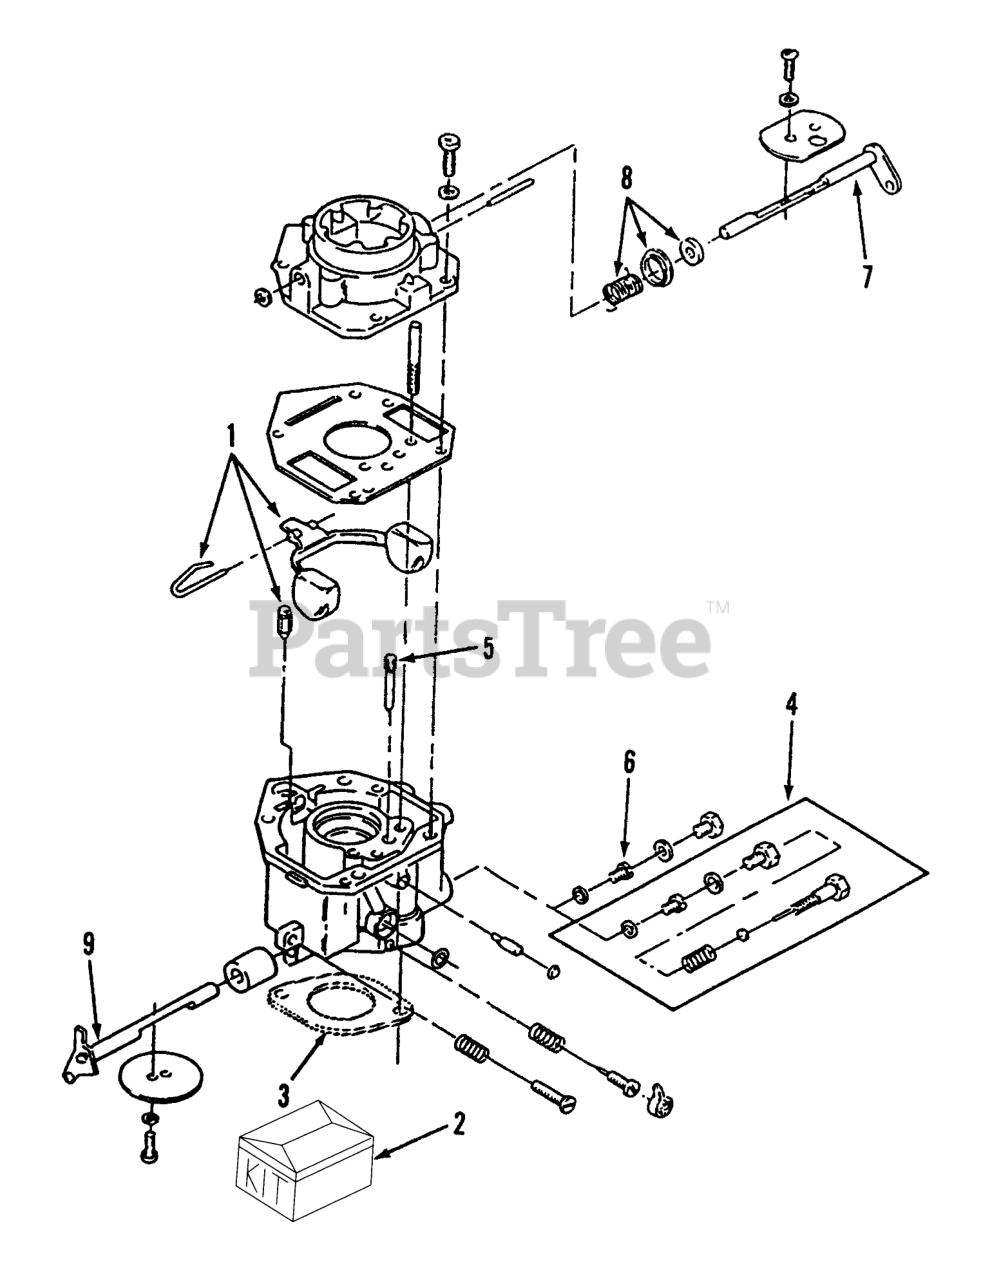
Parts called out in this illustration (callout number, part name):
1	Kit-Float (Includes Float, Pin,& Valve)
2	Kit-Repair (Includes Screw & Plug Package, Gasket Package, Float Valve, Idle Adjust Needle & Spring, Mounting Gaskets, & Idle Limit Cap)
3	Oil Fill Tube
4	FIXED-JET
5	IDLE-JET
6	POWER JET
7	Kit-Shaft, Choke (Includes Choke Valve, Valve Setscrew, & Air Filter)
8	Kit-Lever, Choke (Includes Choke Lever Ring, Choke Spring, & Choke Collar)
9	Kit-Shaft, Throttle (Includes Valve Setscrew, Air Filter, & Throttle Valve)
